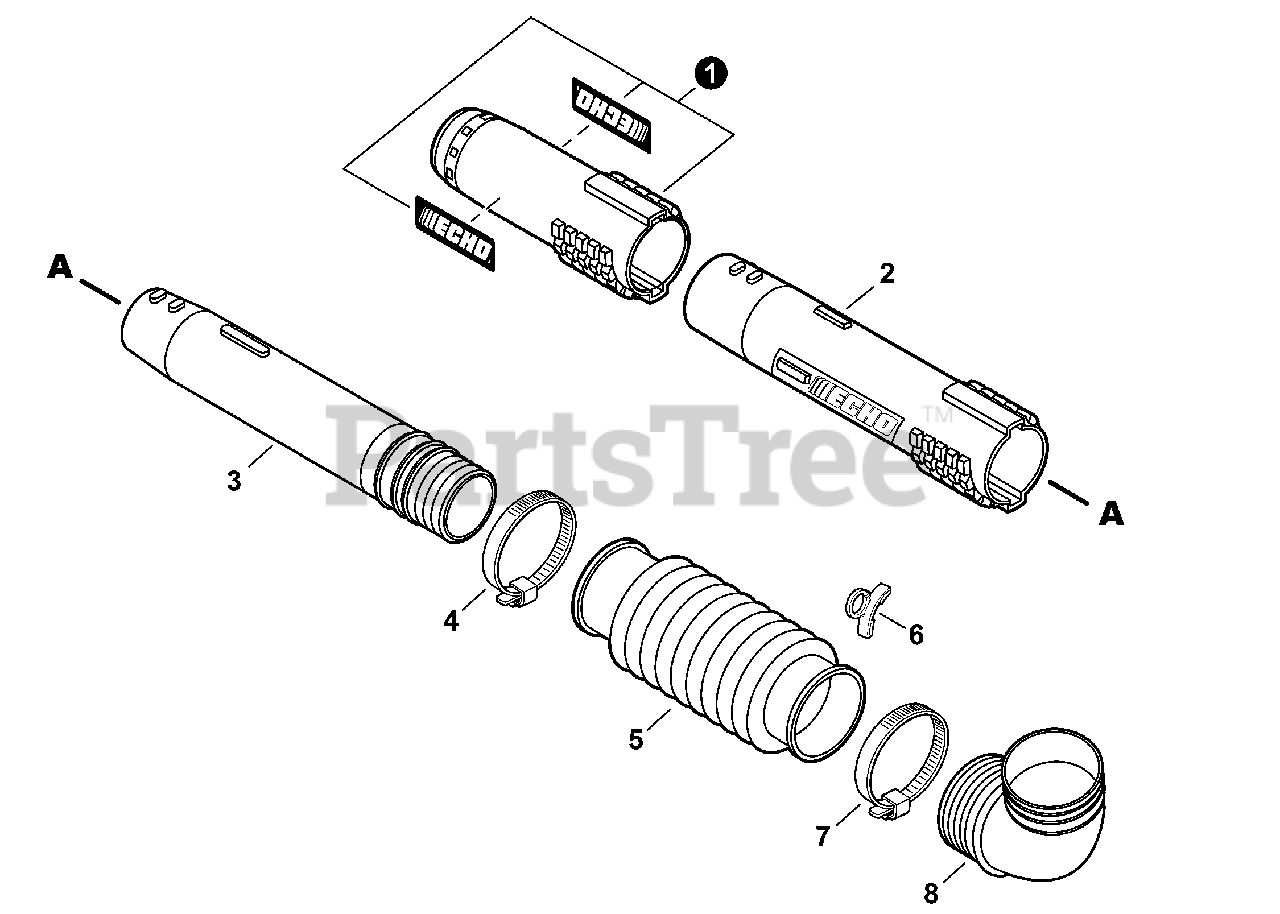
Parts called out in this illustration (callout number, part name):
1	TUBE SET, BLOWER - NOZZLE
2	TUBE, BLOWER - STRAIGHT
3	TUBE, BLOWER - SWIVEL
4	CLAMP 58.7 MM / 82.5 MM
5	TUBE, BLOWER - FLEXIBLE
6	CLIP, CABLE
7	CLAMP - BAND
8	TUBE, BLOWER - ELBOW
